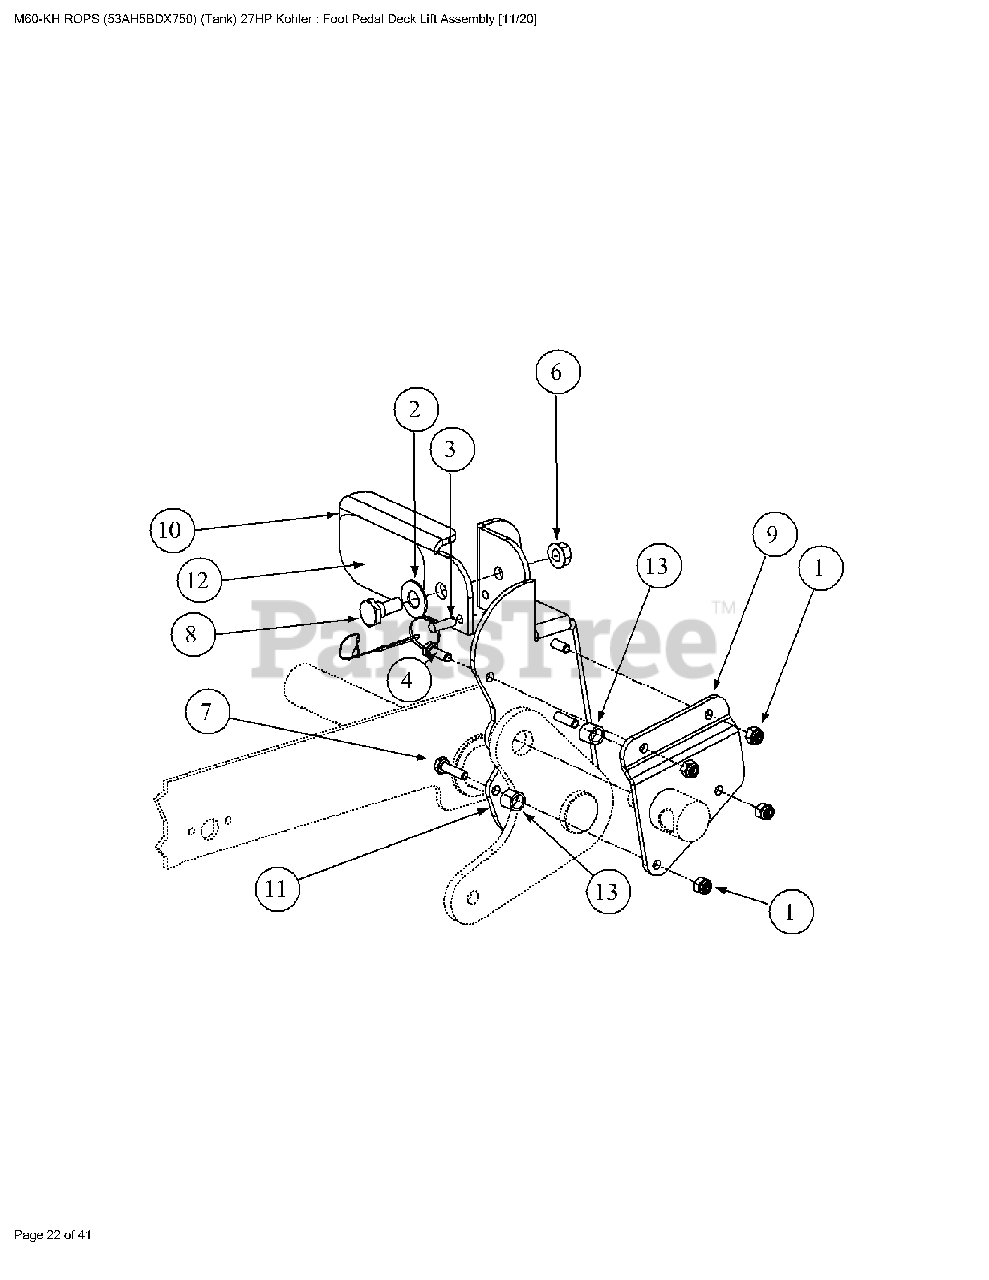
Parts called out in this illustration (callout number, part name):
1	Lock Nut, Nylon Insert, 1/4-20
2	Washer, 1/2 x 1 Shim
3	Detent Pin w/12" Lanyard
4	Hex Cap Screw, 1/4-20, .75
6	Hex Nut, Flange Lock 3/8-16
7	Hex Cap Screw, 1/4-20, 1.00
8	Shoulder Screw, .50 x .27 Lg., 3/8-16
9	Foot Lift Backup Pedal
10	Deck Foot Pedal Lift
11	Deck Foot Pedal Lift
12	Deck Foot Lift Pad
13	Turnbuckle Sleeve
